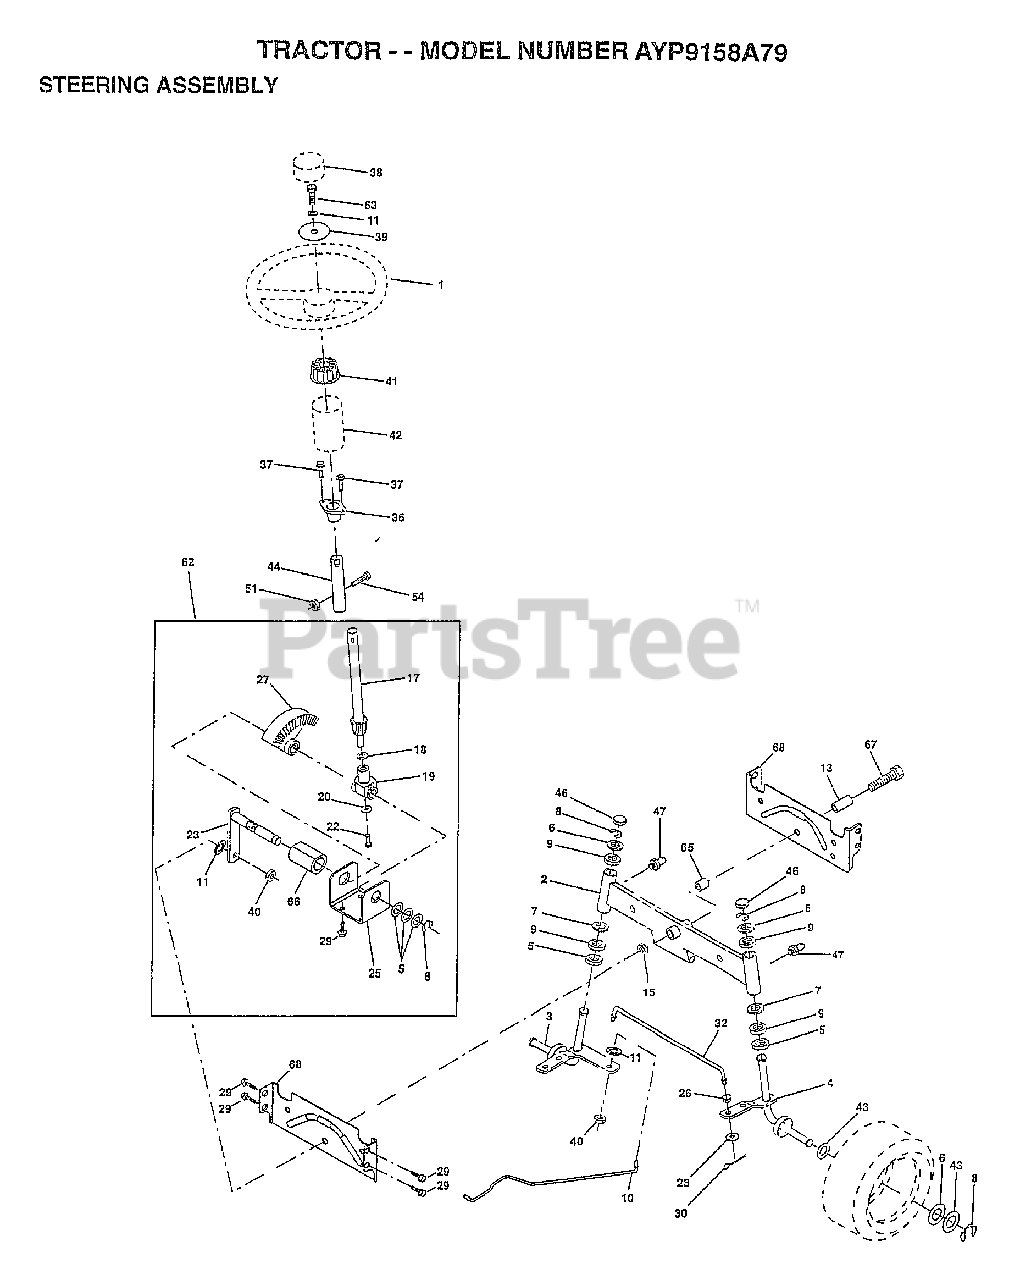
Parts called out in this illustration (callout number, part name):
1	WHEEL STR AYP BLK
2	AXLE ASM
5	WASHER .T
6	WASHER
7	WASHER
8	RING
9	COL. SRTG. BEAR.
10	DRAGLINK-STAMPED
11	LOCKWASHER
13	BEARING AXLE
15	"NUT-LOC,FLANGE LT"
16	AXLE PIN
17	SHAFT ASM STEERIN
18	THRUST WASHER
19	SUPPORT.SHAFT
21	LOCKWASHER
22	SCREW.SCKTHD.CAP
25	BRKT-STEERING
26	BUSHING.DRAGLINK
27	GEAR SECTOR
28	WASHER
29	SCREW
30	COTTER PIN
32	TIE ROD
36	BUSHING.STEERING
37	"SCREW-TT,10-32 FL"
38	CAP STEER AYP
39	WASHER T
40	GRIPCO NUT
41	ADAPTER LT
42	BOOT.STEER.PL
43	WASHER
44	EXT SHAFT STEERIN
46	CAP
47	ZERK M
51	NUT
54	BOLT
62	KIT STEERING ASM
63	BOLT
65	SPACER AXLE
66	"BEARING-ARM,PITMA"
67	BOLT
68	BRACE AXLE
